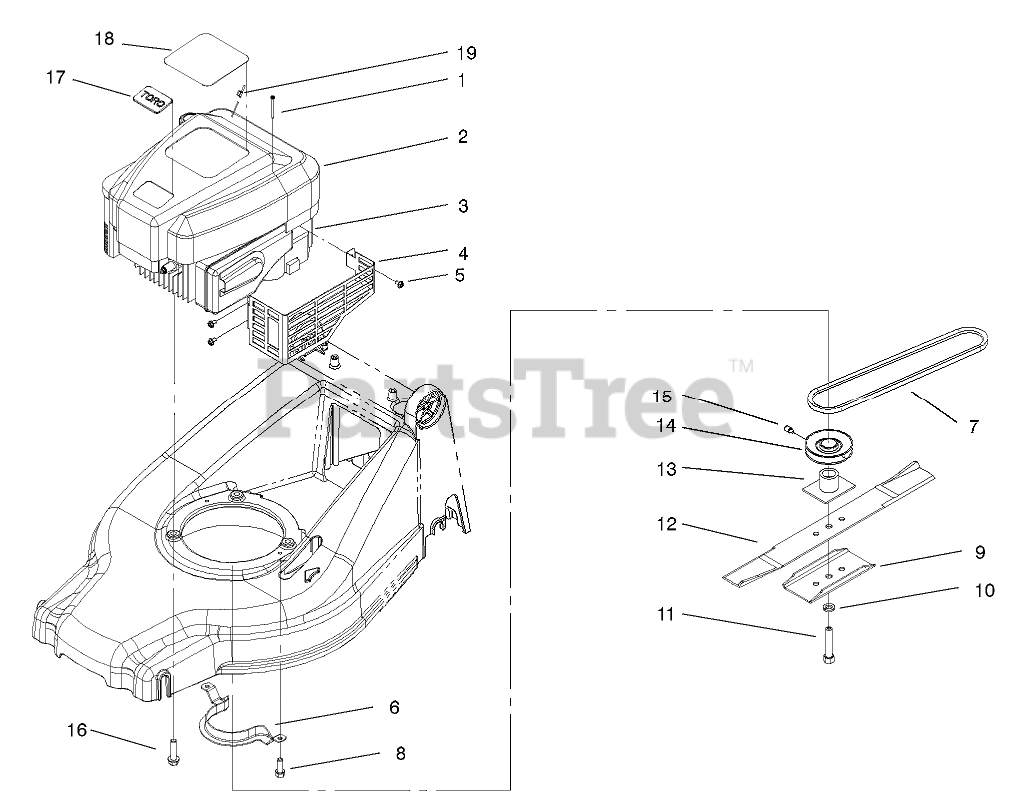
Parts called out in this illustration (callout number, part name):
1	SCREW-PPH
2	SHROUD-ENGINE
4	SHIELD-MUFFLER
5	SCREW-HWH
6	GUIDE-BELT, ENGINE
7	V-BELT
8	SCREW-HWH
9	STIFFENER-BLADE
10	WASHER-LOCK
11	BOLT-BLADE
13	RETAINER-BLADE
14	PULLEY ASM
15	SCREW-SET
16	SCREW-HWH
17	PLATE-LOGO
18	DECAL-ENGINE
19	STOP-ROPE
